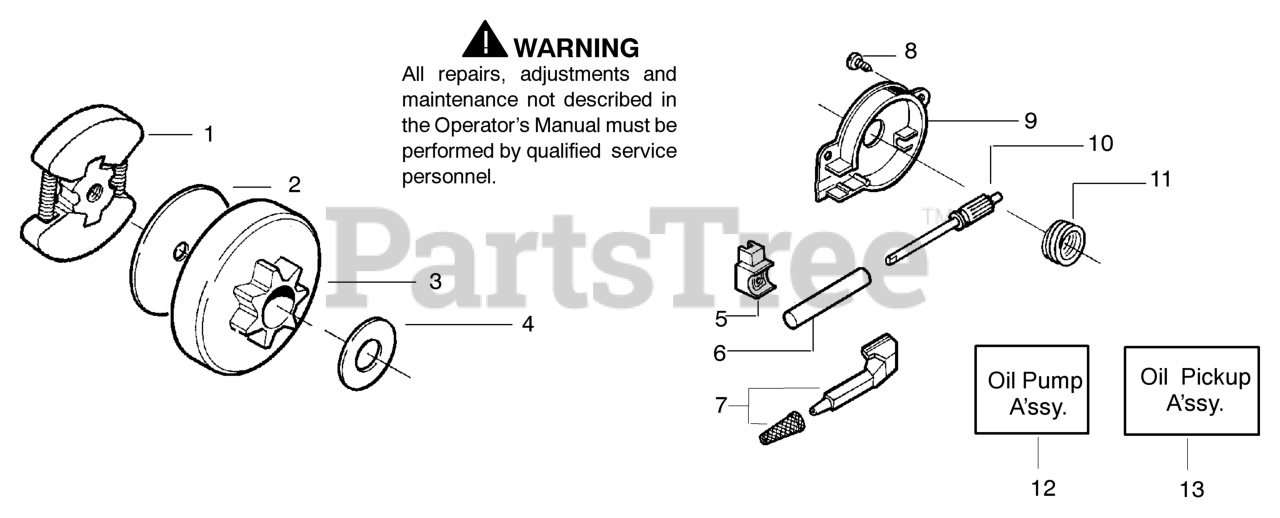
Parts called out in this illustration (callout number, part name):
1	CLUTCH ASSEMBLY
2	FRICTION DISC,CLUTCH 36/41
3	CLUTCH DRUM ASSY
4	THRUST WASHER
5	PRESSURE SEAL,OILER 36/41
6	OIL PUMP BARREL
7	OIL PICKUP
9	OIL PUMP HOUSING
10	PLUNGER & GEAR ASSEMBLY
11	OILER GEAR 36/41
12	OILER ASS'Y 36/41
13	SERVICE KIT-OIL PICKUP 36/41
